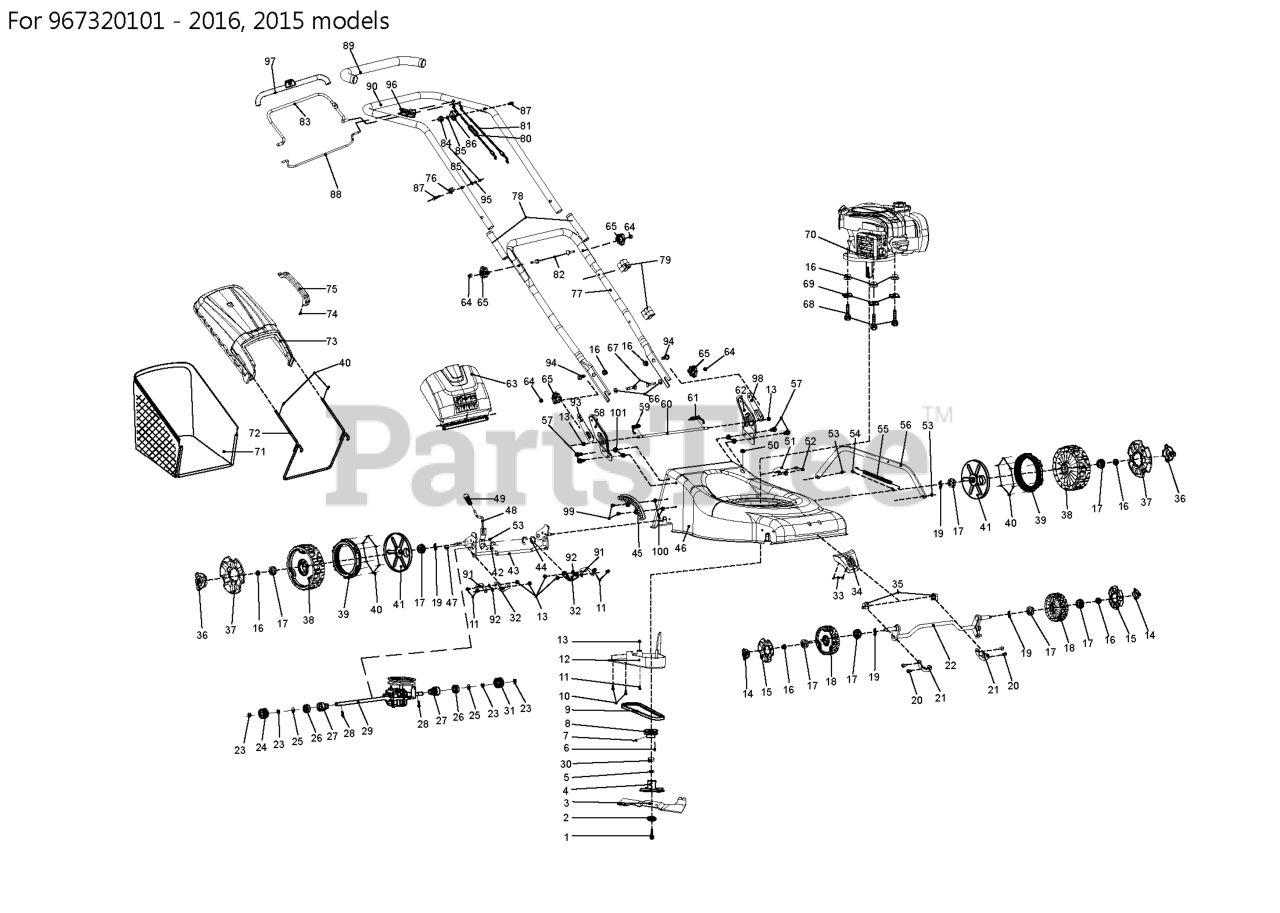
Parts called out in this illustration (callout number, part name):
11	SCREW M6*16 #26800204601
13	LOCK NUT M6,GB/T6187.1-2000 #2
14	WHEEL COVER 6" #25340700101
16	LOCKING BOLT M8,GB6187.1 #2680
19	WASHER Ï?12 #26800706202
23	WASHER Ï?9,GB896 #26800900201
25	WASHER Ï?12.8*Ï?20*0.8 #268007
27	BEARING HOUSING #26900211501
32	FIXING PLATE #26300124401
36	WHEEL COVER 8" #25341000101
37	WHEEL COVER 8" #25341100101
38	WHEEL 8" #25341200101
39	GEAR WHEEL #25229900201
41	COVER #25342800101
42	WASHER Ï?19*1.5,GB896 #2680090
44	WASHER #26300107601
45	SEGMENT #25214200102
47	WASHER M6*14 #26800203001
49	KNOB HEIGHT ADJUSTMENT #25341
50	COVER #25217800104
52	BOLT M6*12,(GB5787-86)GB6674.1
53	LOCKING BOLT M6,GB889.1 #26800
54	TUBING #29000300101
55	SPRING #26801103903
57	BOLT M8*16 #26800606401
58	BRACKET RH
59	SPRING #26801125501
61	BRACKET #26801125401
64	HEXAGON NUT #26800502301
65	KNOB #25341500101
66	SPACER RING
71	GRASSBAG #25100173001
72	BRACKET #26300299201
73	COVER GRASS CATCHER #253417001
74	SCREW ST4.8*19,GB845 #26800104
75	HANDLE #25341800101
79	HOLDER CABLE
92	O-RING #25100175201
93	PLATE RIGHT
98	PLATE LEFT
